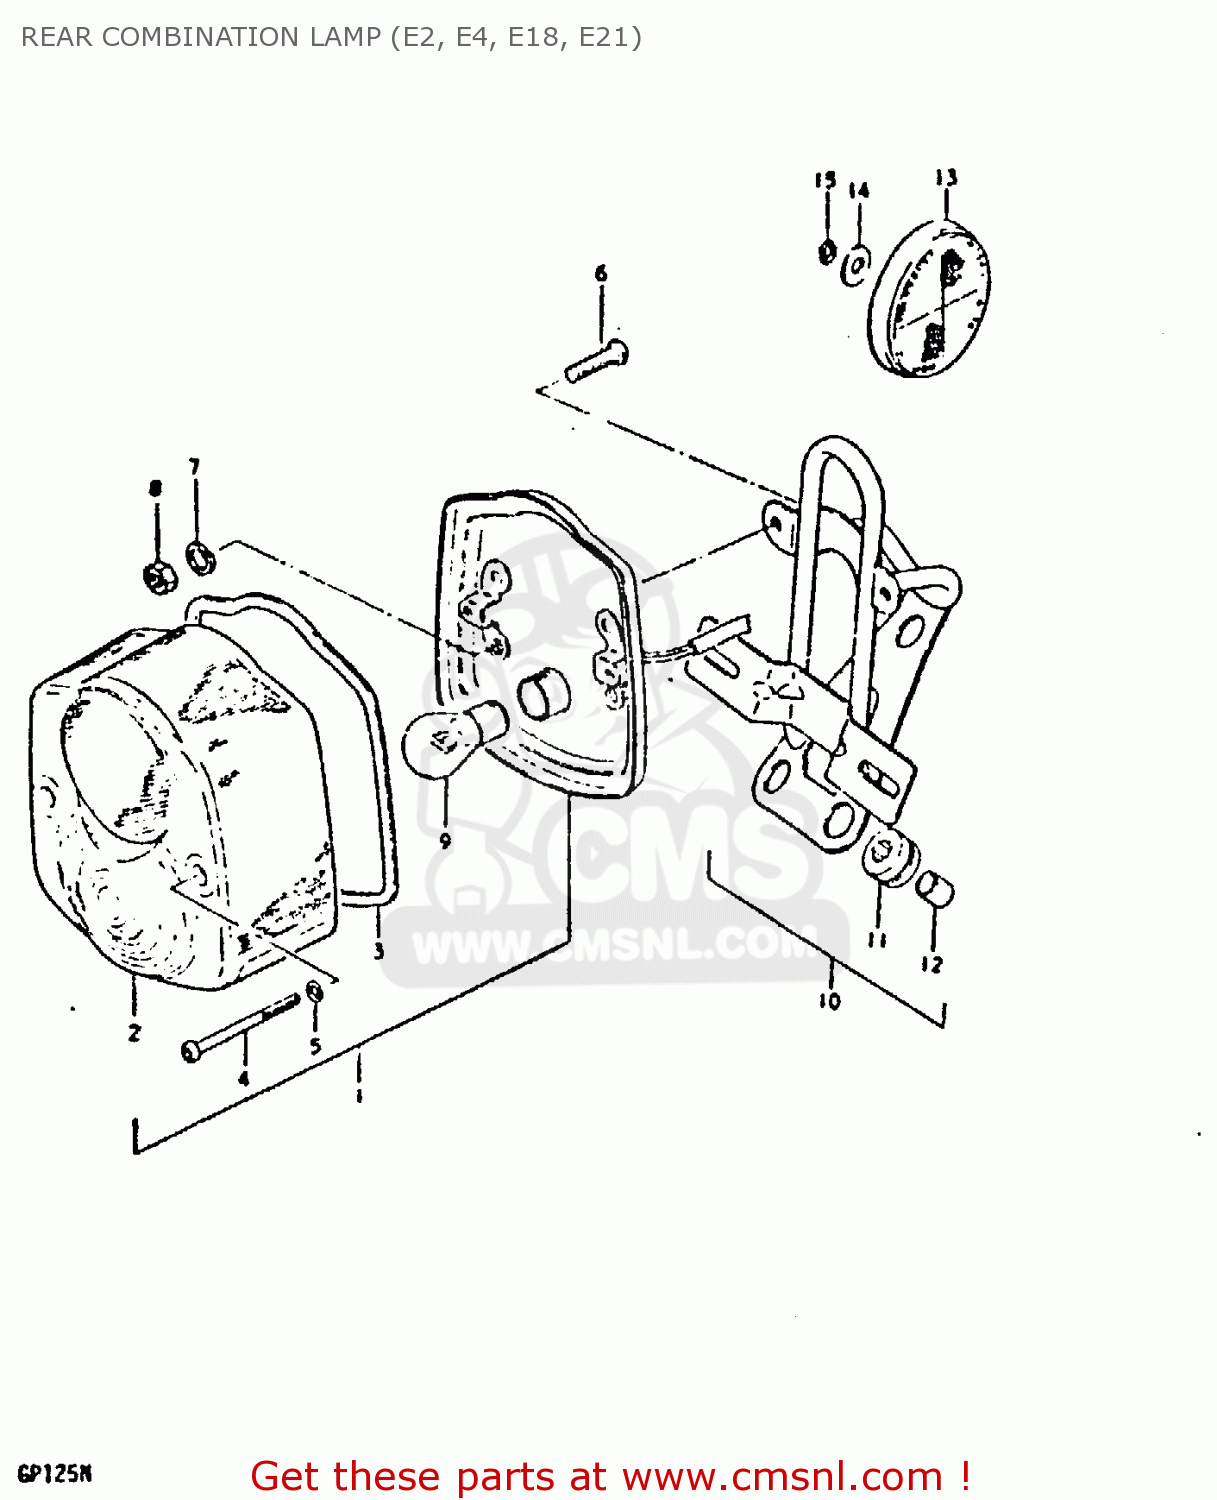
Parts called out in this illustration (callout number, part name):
1	LAMP ASSY, REAR COMBINATION
2	LENS
3	GASKET (NAS)
4	SCREW
5	GASKET (NAS)
9	BULB (6V,21/5W)
